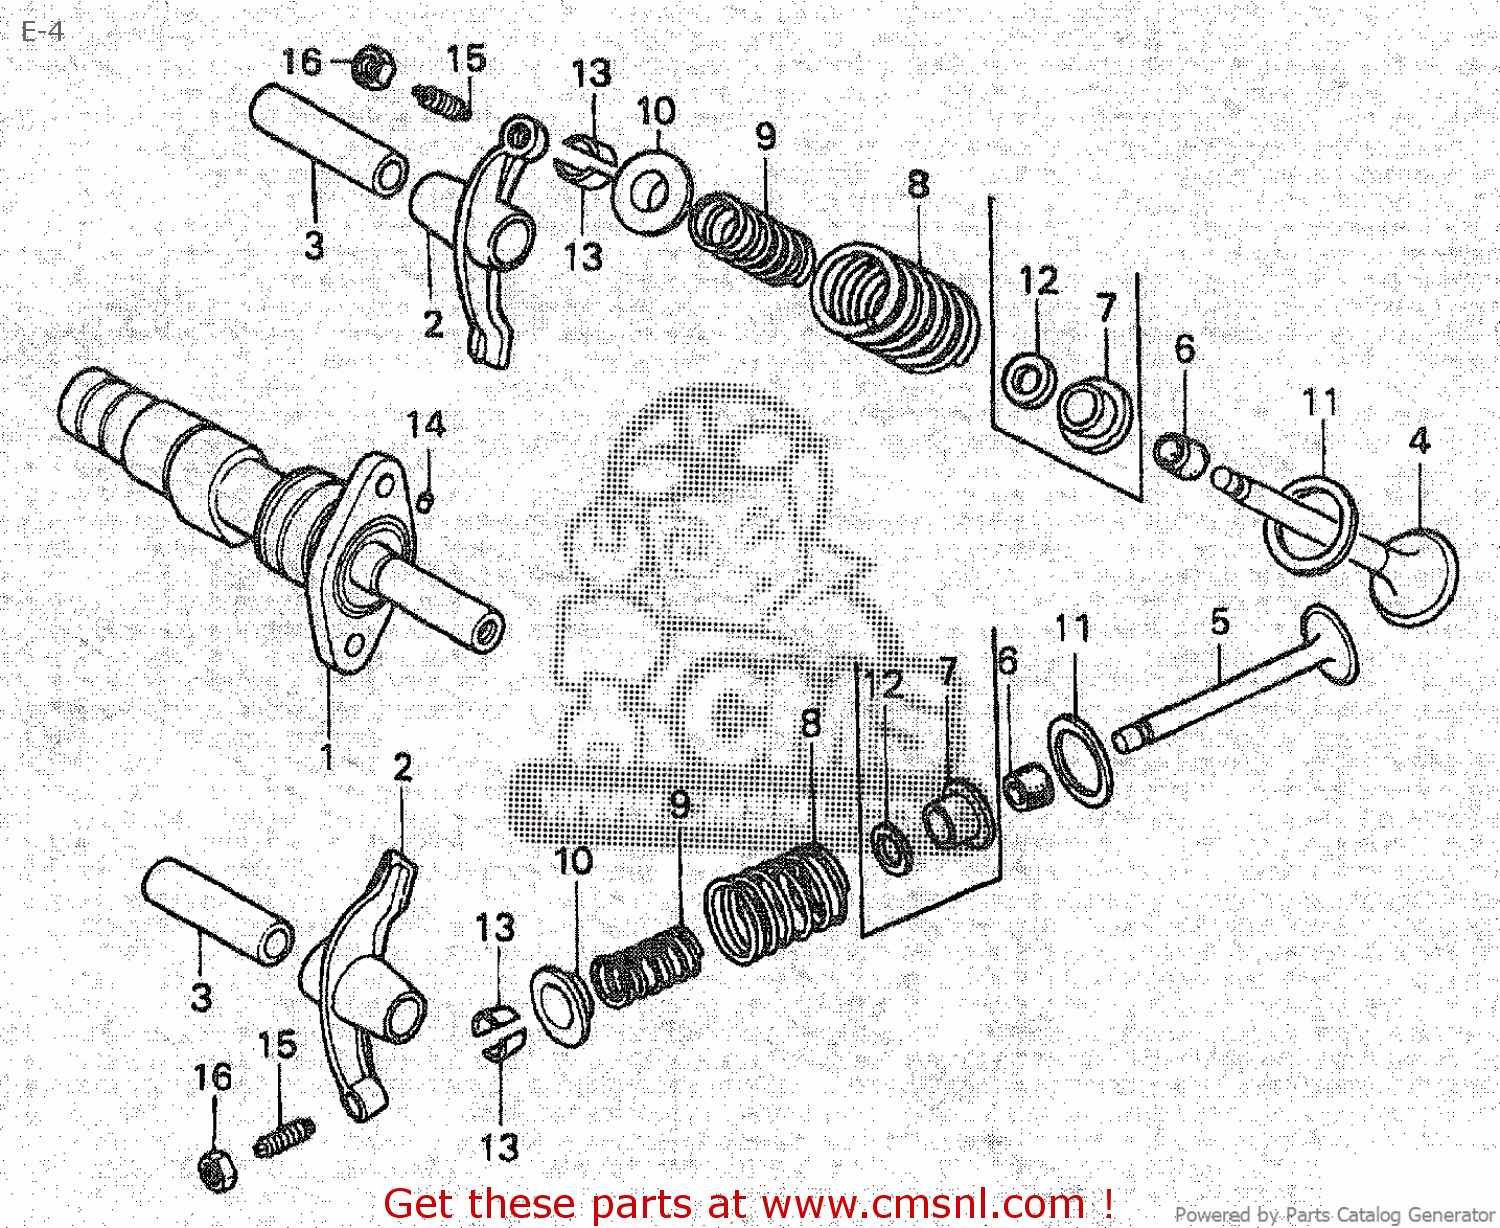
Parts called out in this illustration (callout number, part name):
1	CAMSHAFT
2	ARM,VALVE ROCKER
3	SHAFT, ROCKER ARM
4	VALVE,INLET
5	VALVE,EXHAUST
6	SEAL,VALVE STEM
7	CAP, VLV. STEM
8	SPRING VALVE
9	SPRING IN VALVE
10	RETAINER SPRING
11	SEAT, VLV. SPRING
12	SEAT, VLV. SPRING
13	COTTER, VALVE
14	PIN, KNOCK, 3X5.2
15	SCREW,TAPPET ADJ.
16	NUT, TAPPET.
